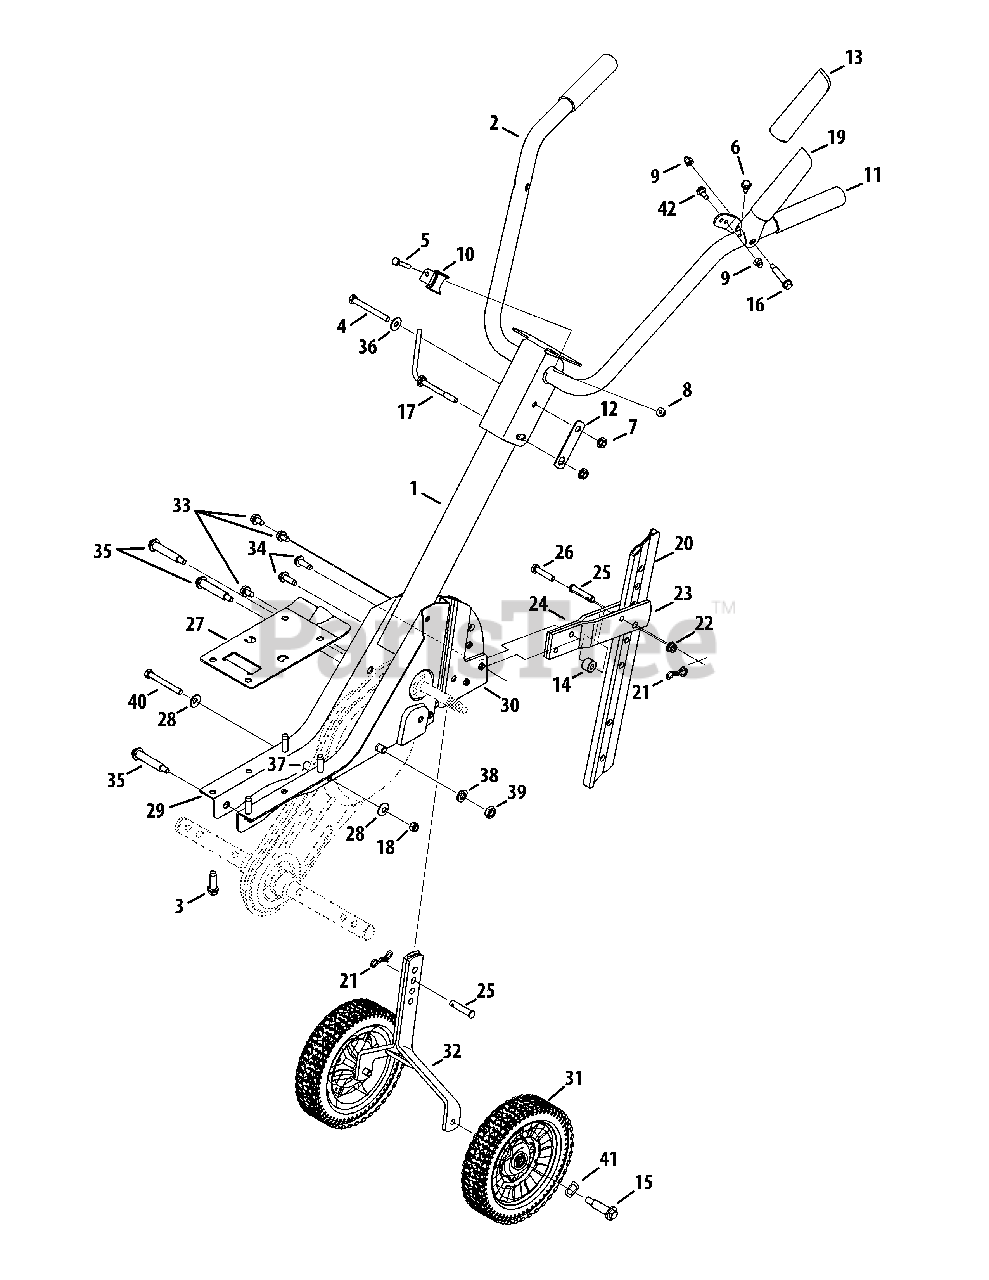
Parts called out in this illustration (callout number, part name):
1	Handle Tube Assembly
2	Handle Handle Assembly
3	Screw, 3/8-16 x 1.250
4	Hex Cap Screw, 5/16-18 x 3
5	Hex Head Screw, 1/4-20 x 1.50
6	Screw, 1/4-14 x .625
7	Hex Flange L-Nut, 5/16-18
8	Flangelock Nut, 1/4-20
9	Acorn Lock Nut, 1/4-20
10	Rope Guide
11	Grip, 1.0 x 5.0
12	Retainer Bracket
13	Grip, Handle
15	Shoulder Screw, .496 x 1.445
16	Shoulder Screw, .375 x 1.355, 1/4-20
17	Handle Adjustment Crank
18	Nylon Hex Nut, 5/16-18
19	Clutch Lever Assembly
21	Cotter Pin, Bow Tie
22	Hex Flange L-Nut, 5/16-18
23	Tail Piece Bracket, Left
24	Tail Piece Bracket, Right
25	Clevis Pin
26	Hex Bolt, 5/16-18 x 1.5"
28	Bell Washer, .340" x .872"
31	Wheel, 8 x 1.75, Bar Tread
32	Wheel Hanger Bracket Assembly
33	Screw, Self-tapping, 5/16-18, .750,
34	Hex Washer TT-Tap Screw
35	Shoulder Bolt, 5/16-18
36	Bell Washer, .34"
38	Lock Washer, 7/16
39	Jam Nut, 7/16-20
40	Hex Cap Screw, 5/16-18 x 3
41	Wave Washer .531 x .781 x .013
42	Shoulder Screw, .3175 x .188, 1/4-20
